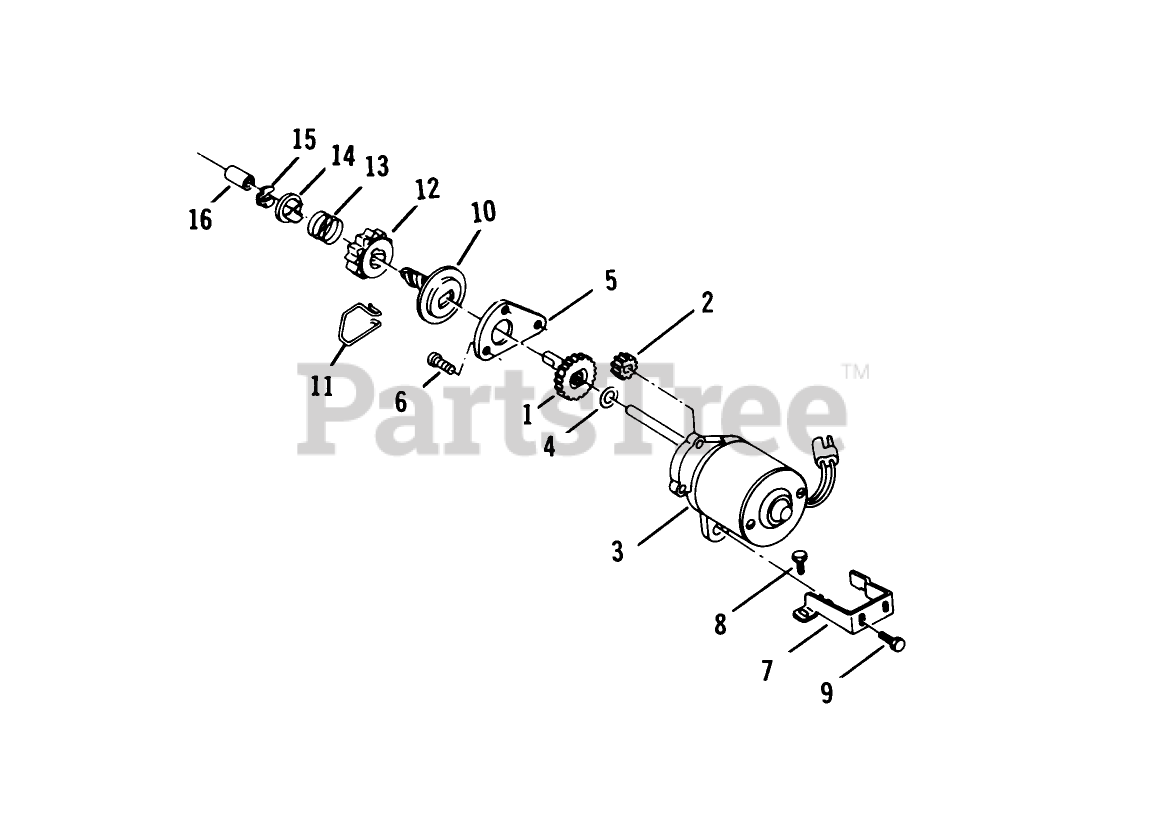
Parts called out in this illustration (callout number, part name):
1	GEAR-DRIVEN
2	*PINION EF
6	SCREW EF
7	BRACKET EF
9	SCREW-SEMS
11	SPRING F
12	PINION EF
13	*SPRING PINION EF
15	RET.RING EF
16	SLEEVE F
